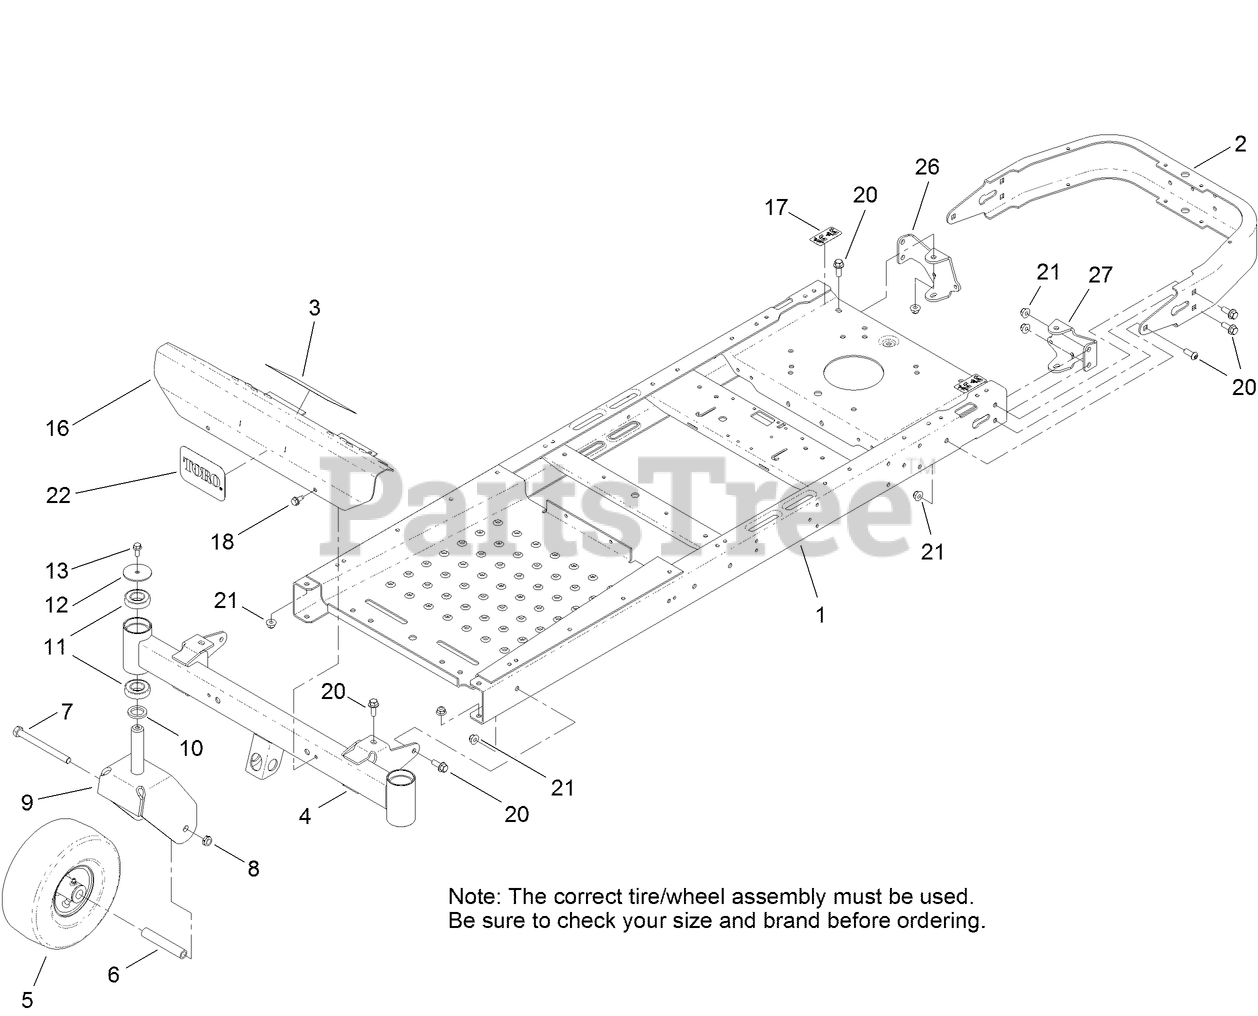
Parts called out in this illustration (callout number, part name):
2	BUMPER-REAR
4	AXLE-FRONT
5	CASTER WHEEL ASM (CST)
5	CASTER WHEEL ASM
6	BUSHING-SPANNER
7	SCREW-HH
8	NUT-HEX
9	FORK-CASTER
10	WASHER-THRUST
11	BEARING-BALL
12	WASHER
13	SCREW-HHF
17	DECAL-BYPASS
18	SCREW-HWHTF
20	SCREW-HHF
21	NUT-HF, NI
26	MOUNT-HYDRO, REAR (RH)
27	MOUNT-HYDRO, REAR (LH)
